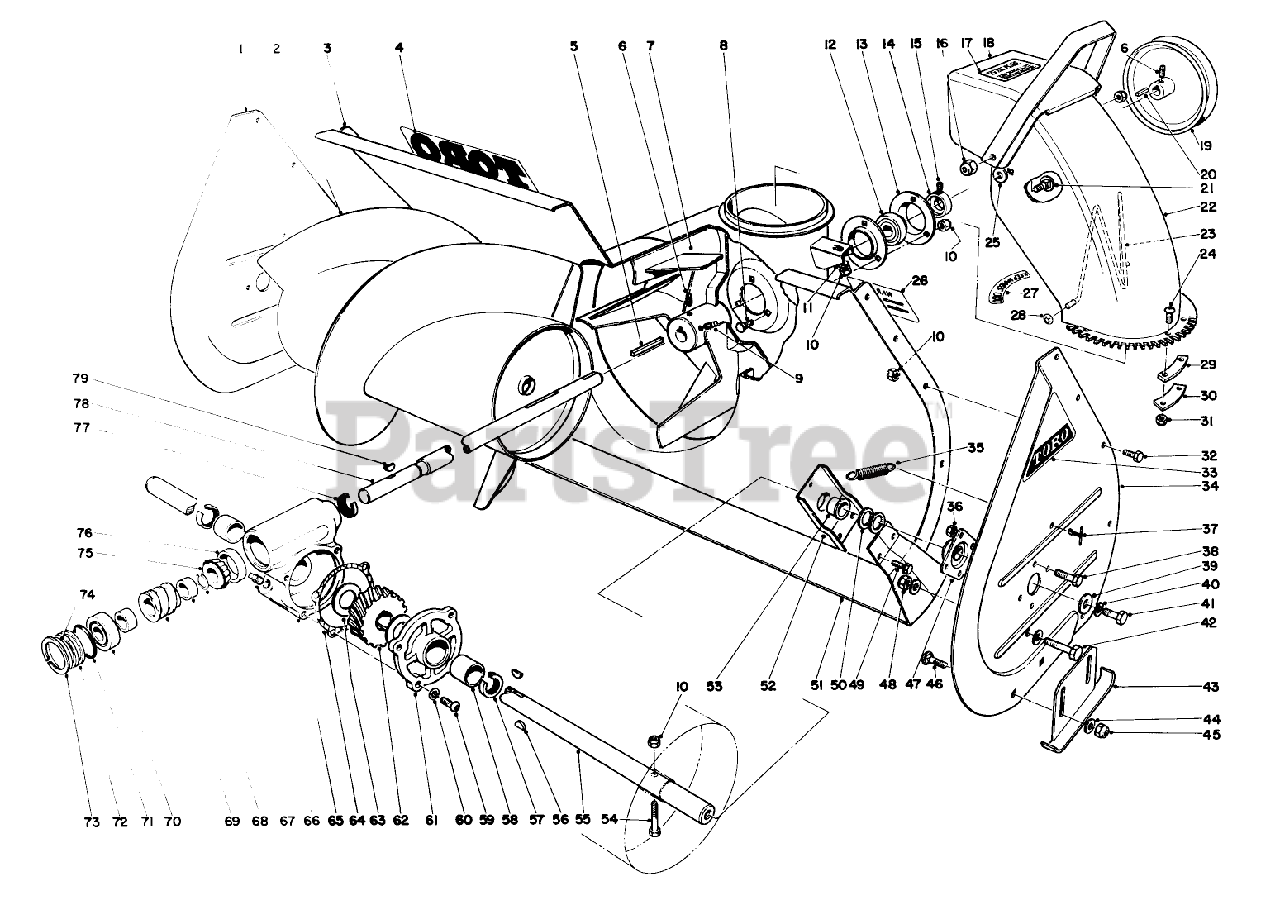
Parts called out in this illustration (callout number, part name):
4	Decal
6	SCREW-SET, SQH
8	BOLT-CARR
9	SCREW-SET, SQH
11	WASHER-LOCK
12	BALL BRG W/COLLAR
13	BRG FLANGE
14	EXT LOCKING COLLAR
15	SCREW-HSH
16	NUT-LOCK, NI
20	SQUARE KEY
21	SCREW-CARR
23	WIRE-CHUTE
24	SCREW-HSBH
25	WASHER-FLAT
27	Decal
28	NUT-PUSH
29	CHUTE TAB SPACER
32	SCREW-HH
35	SPRING-TENSION
38	SCREW-HH
39	WASHER
40	WASHER-LOCK
41	SCREW-HH
42	SCREW-HH
44	WASHER-FLAT
45	NUT-LOCK, NI
46	BOLT-CARR
50	Spacer
51	Scraper Blade
53	BUSHING-FLANGE
54	SCREW-HH
55	26 AUGER SHAFT
56	KEY-WOODRUFF
57	SEAL-OIL
59	SCREW-HSBH
60	WASHER-LOCK
62	GEAR-WORM, 27T
63	WASHER-THRUST
65	Gear Box, Auger (Incl. Ref 58 76)
66	PLUG-PIPE, SQH
67	RETAINER RING
70	.750 BALL BEARING
71	O-RING
73	INTRNL RETAINING RING
75	3/4 ROLLER BRG CONE
77	SEAL-OIL
79	KEY-WOODRUFF
